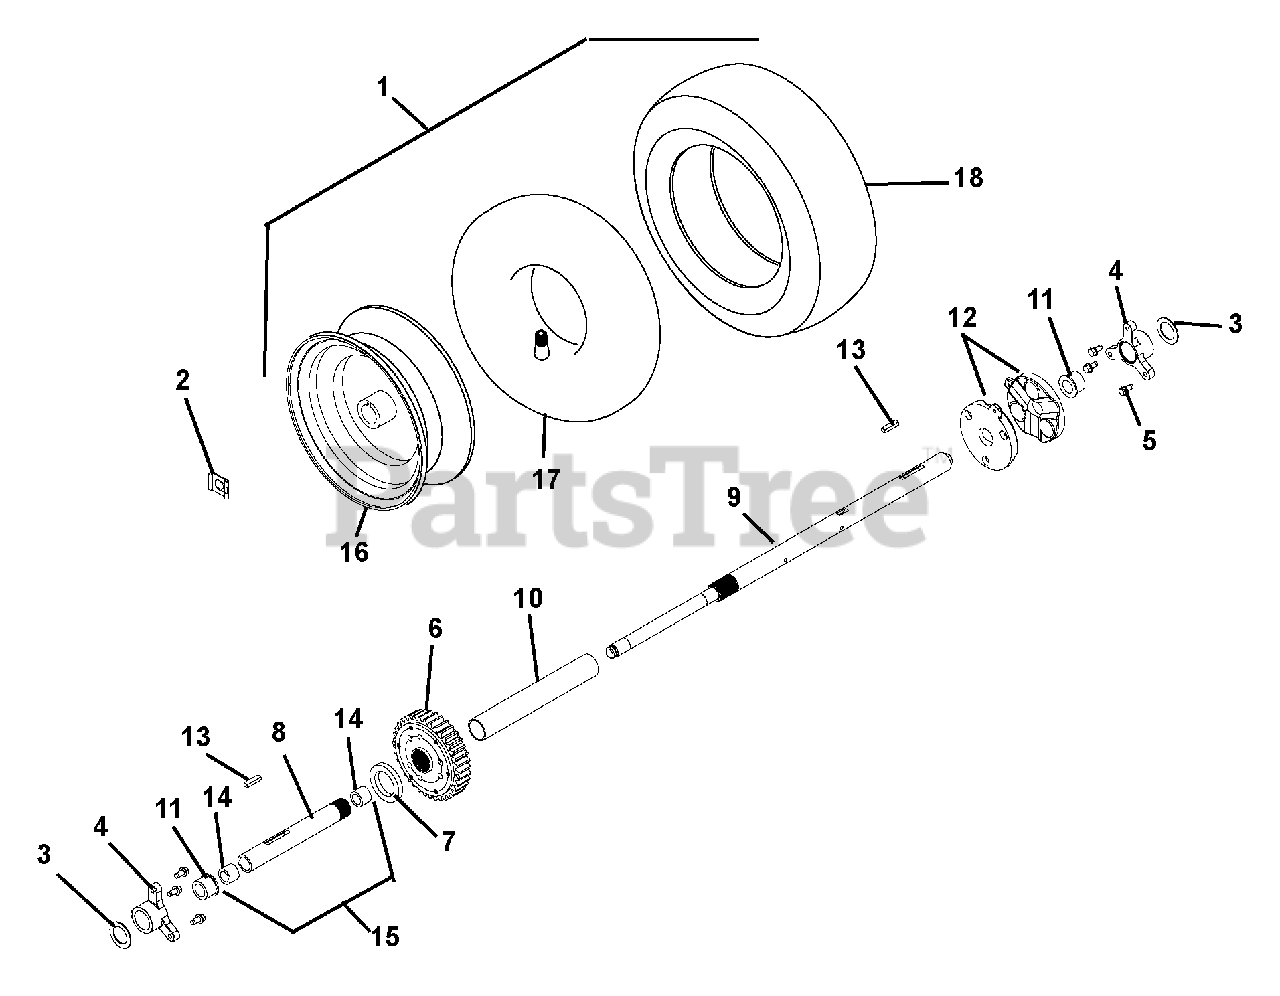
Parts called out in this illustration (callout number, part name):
1	TIRE/WHEEL, RH 16X4.80-8 DIFF
2	CLIP, SNAP .625 DIA
3	WSHR-FL-STL 1.010X1.505X.062YZ
4	BUSHING, RAKE SHAFT 1"
5	@SCR-TAP .25-20X.50 HWH TR YWZ
6	DIFFERENTIAL, REMOTE-ASSY
7	WSHR-FL-NY 1.38X2.00X.25
8	AXLE, DIFFERENTIAL-SHORT
9	AXLE, DIFFERENTIAL-LONG
10	TUBE, AXLE
11	BSHG-FLG SPLIT NYLINER 1.0" HP
12	CAM, DIFFERENTIAL
13	KEY-RECT .25X.188X1.00
14	BSHG-SLV .706X.764X.75 BRZ
15	AXLE, DIFFERENTIAL-W/BUSHINGS
16	HUB, WHEEL - 16X4.8-8 DIFF
17	TUBE
18	TIRE, X-TRAC 16X4.8-8
